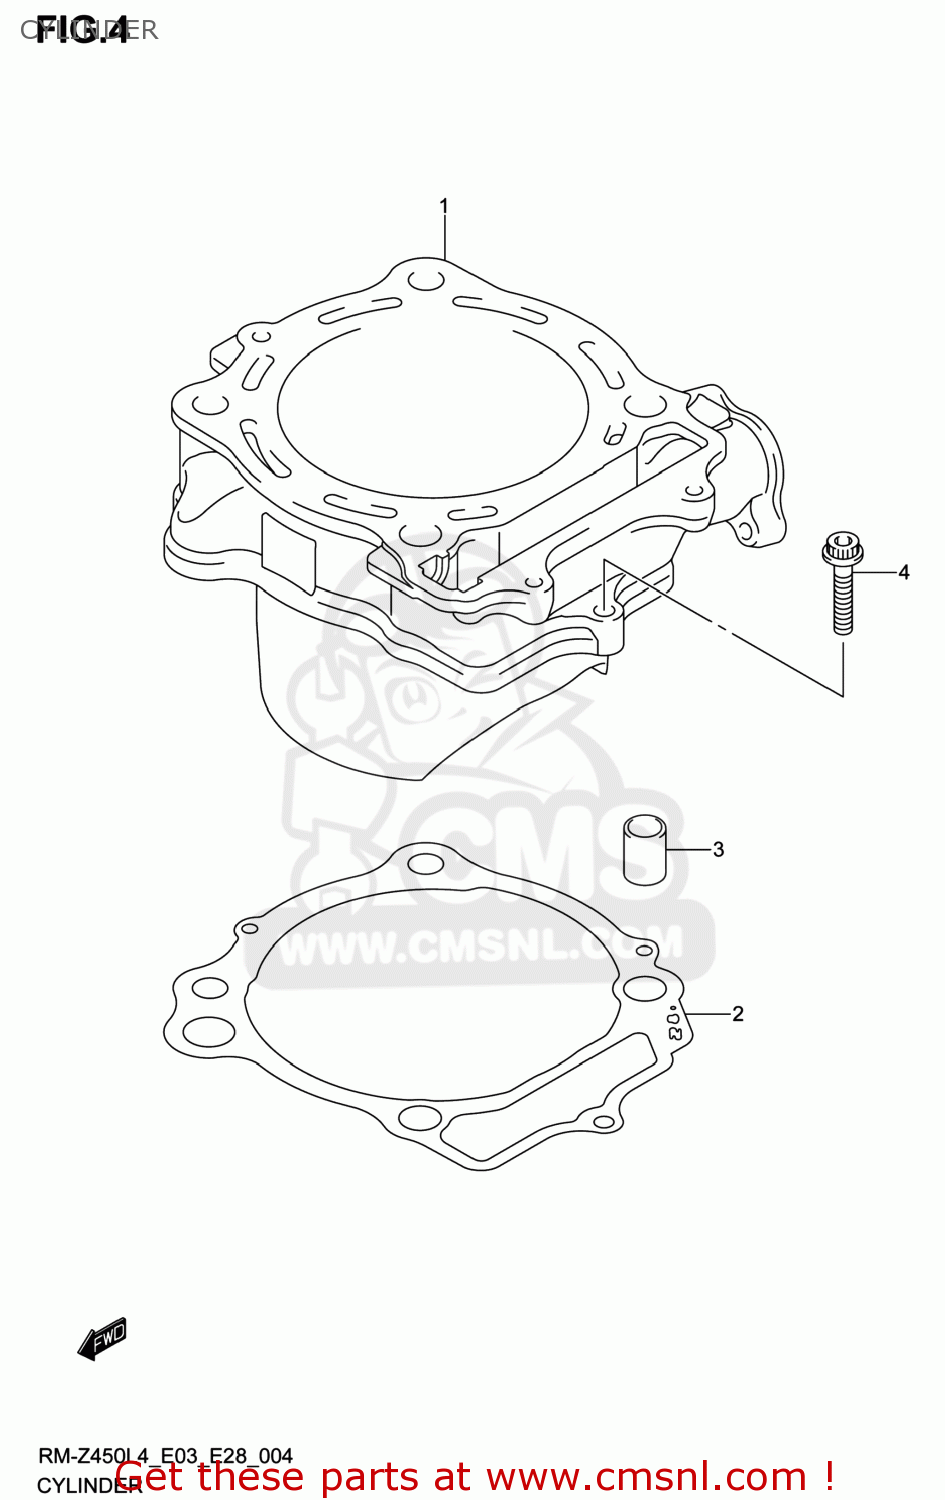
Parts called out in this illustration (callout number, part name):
1	CYLINDER
2	GASKET,CYLINDER (NAS)
3	PIN
4	BOLT
